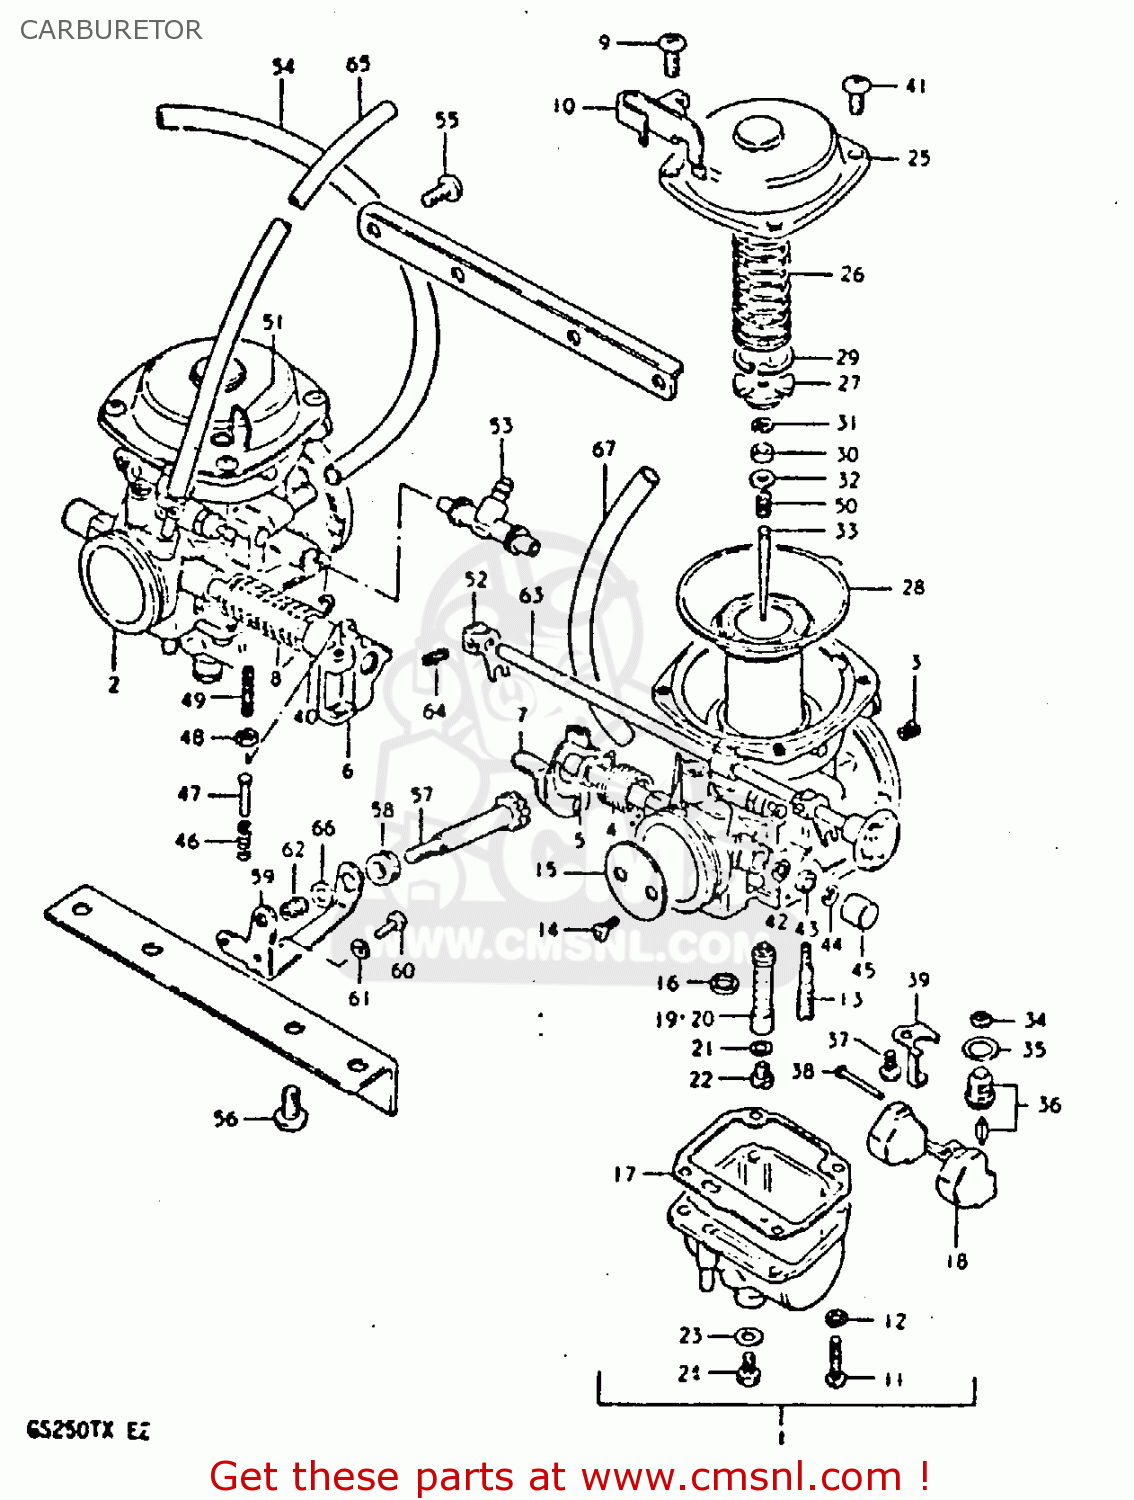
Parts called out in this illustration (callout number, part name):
1	CARBURETOR, LH
2	CARBURETOR, RH
3	JET
4	SPRING
5	RING
6	SHAFT ASSEMBLY
7	SHAFT ASSEMBLY
8	SPRING
9	SCREW
10	BRACKET
11	SCREW
12	LOCK WASHER
13	JET
14	SCREW
15	VALVE,THROTTLE (BUTTERFLY)
16	GASKET (NAS)
17	GASKET,FLOAT CAHMBER (NAS)
18	FLOAT
19	JET,NEEDLE
20	JET,NEEDLE
21	WASHER,NEEDLE NOZZLE
22	JET
23	GASKET (NAS)
24	PLUG,DRAIN
25	COVER,DIAPHRAGM
26	SPRING
27	HOLDER,GUIDE
28	DIAPHRAGM ASSEMBLY
29	E RING
30	RING
31	CLIP,NEEDLE
32	WASHER
33	NEEDLE JET
34	FILTER
35	O RING
36	VALVE ASSEMBLY,NEEDLE
37	SCREW
38	PIN,FLOAT
39	PLATE,NEEDLE VALVE FITING
40	RING,THROTTLE VALVE
41	SCREW
42	SEAL
43	GASKET,THROTTLE SHAFT (NAS)
44	E RING
45	CAP
46	SPRING,THROTTLE SCREW
47	PIN,THROTTLE LEVER
48	NUT
49	SCREW
50	SPRING
51	CLIP,HOSE
52	LEVER
53	NIPPLE,CARBURETOR
54	HOSE
55	SCREW
56	SCREW
57	SCREW,THROTTLE STOP
58	BUSHING,THROTTLE ADJUSTER
59	BRACKET,THROTTLE ADJUST
60	SCREW
61	LOCK WASHER
62	SPRING
63	SHAFT,STARTER
64	SCREW
65	HOSE
66	WASHER
67	HOSE
